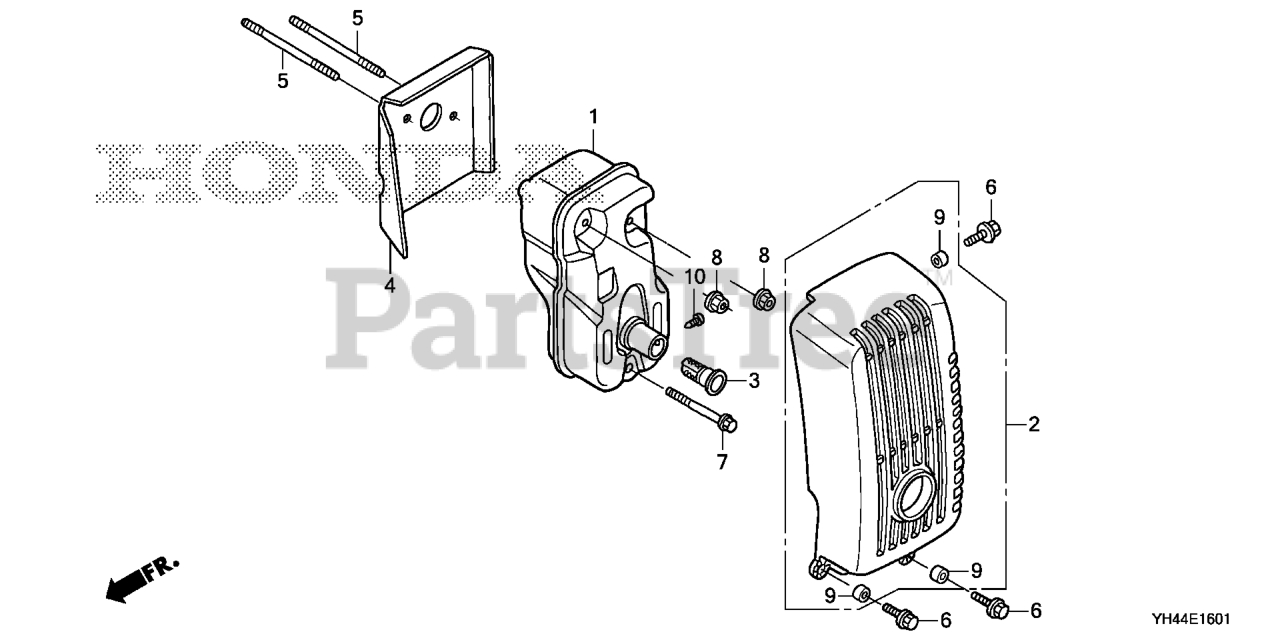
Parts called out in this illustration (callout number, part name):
1	MUFFLER
2	PROTECTOR, MUFFLER
3	ARRESTER, SPARK
4	GUIDE, AIR
5	BOLT 2, STUD (5X55)
6	BOLT, FLANGE (5X16)
7	BOLT, FLANGE (5X35)
8	NUT, SELF-LOCK (5MM)
9	COLLAR, TOP COVER
10	SCREW, TAPPING (4X8)
